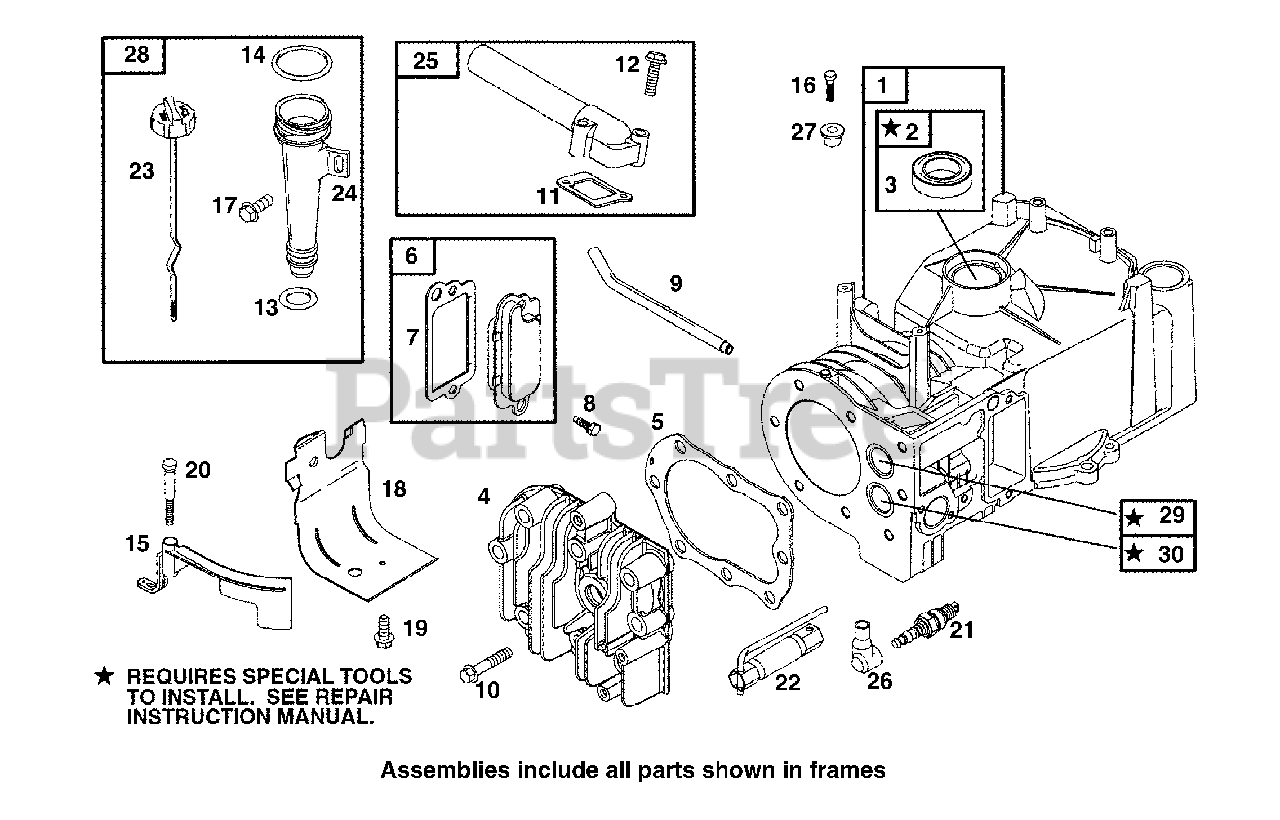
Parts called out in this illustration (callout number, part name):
1	Cylinder Assembly
2	Bushing
3	Oil Seal
4	Cylinder Head
5	Cylinder Head Gasket
6	Breather Assembly
7	Breather Gasket
8	Hex Screw
9	Breather Tube
10	Hex Screw
11	Gasket-Intake
12	Hex Screw
13	Seal-O-Ring
14	Seal-O-Ring
15	Blade-Governor
16	Hex Screw
17	Shoulder Screw
18	Cylinder Shield
19	Hex Screw
20	Shoulder Screw
21	Spark Plug
22	Spark Plug Wrench
24	Oil Fill Tube
25	Manifold-Intake
26	Spark Plug Boot
28	Dipstick/Tube Ass'y
29	Valve Seat (Intake)
30	Valve Seat (Exhaust)
